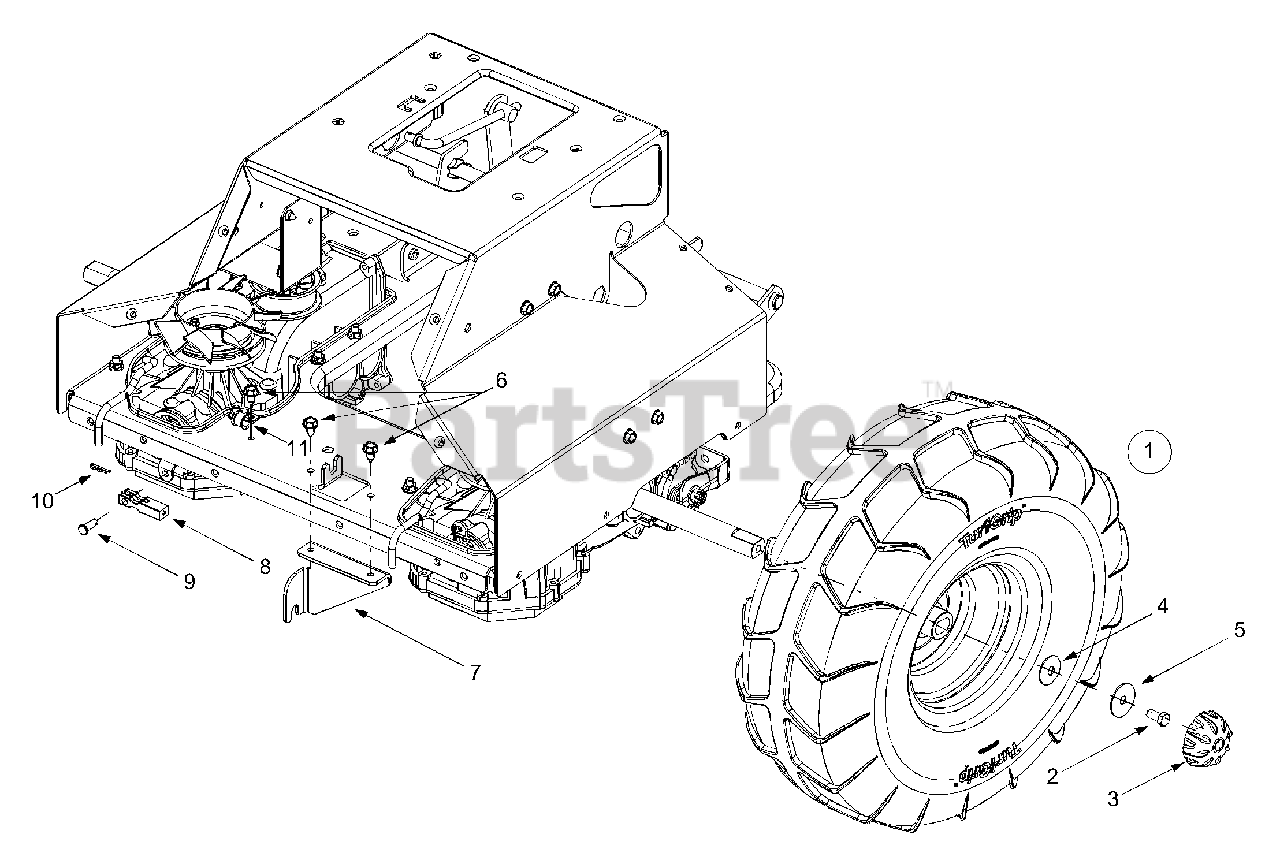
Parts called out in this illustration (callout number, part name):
1	Tire Only, 20.4 x 7.0 x 8.0 Turf-Grip
2	Hex Cap Screw, 3/8-24 x .75
3	Hub Cap
4	Bell Washer, .391 x 1.38 x .062
5	Flat Washer, .410 x 1.59 x .062
6	Self-tapping Screw, 16-18 x .625
9	Clevis Pin, .3125 x .81
10	Internal Cotter Pin, 5/16
11	Clamp, 9/16
